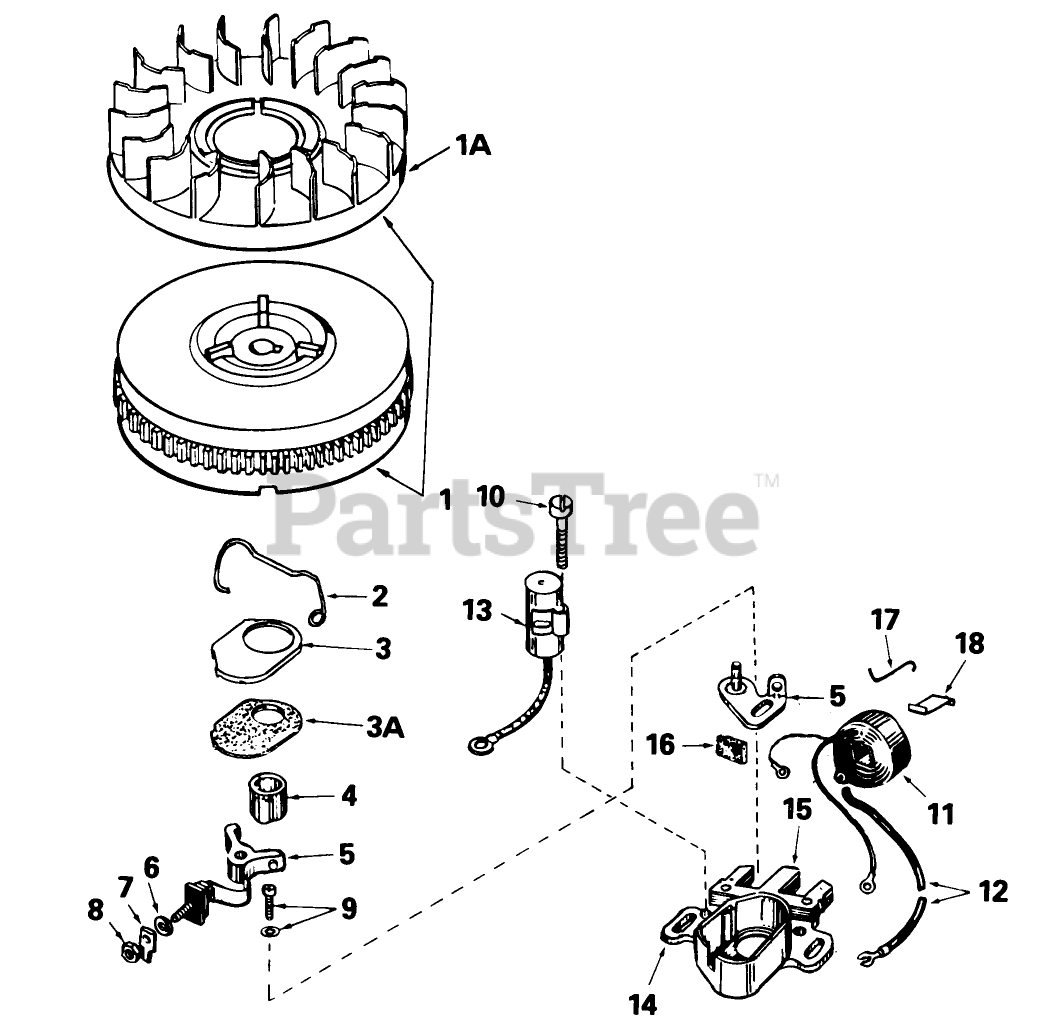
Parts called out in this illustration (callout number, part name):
1	Flywheel (Incl. Ref. #1A)
2	Spring Breaker Box
3	Cover-Dust
3A	Gasket-Dust Cover
4	Cam-Breaker
5	Breaker Assy.
6	Washer
7	Terminal, Ground
8	DECAL
9	Breaker Screw
10	Condenser Screw
11	Coil Assy. (Incl. No. 12)
12	Wire, Lead
13	Condenser
14	Core Plate
15	Stator Assy. (Incl. Ref. #2 thru 11, 13, 14, 16, 17 19)
16	Felt,Cam Wiper
17	Clip, Coil
